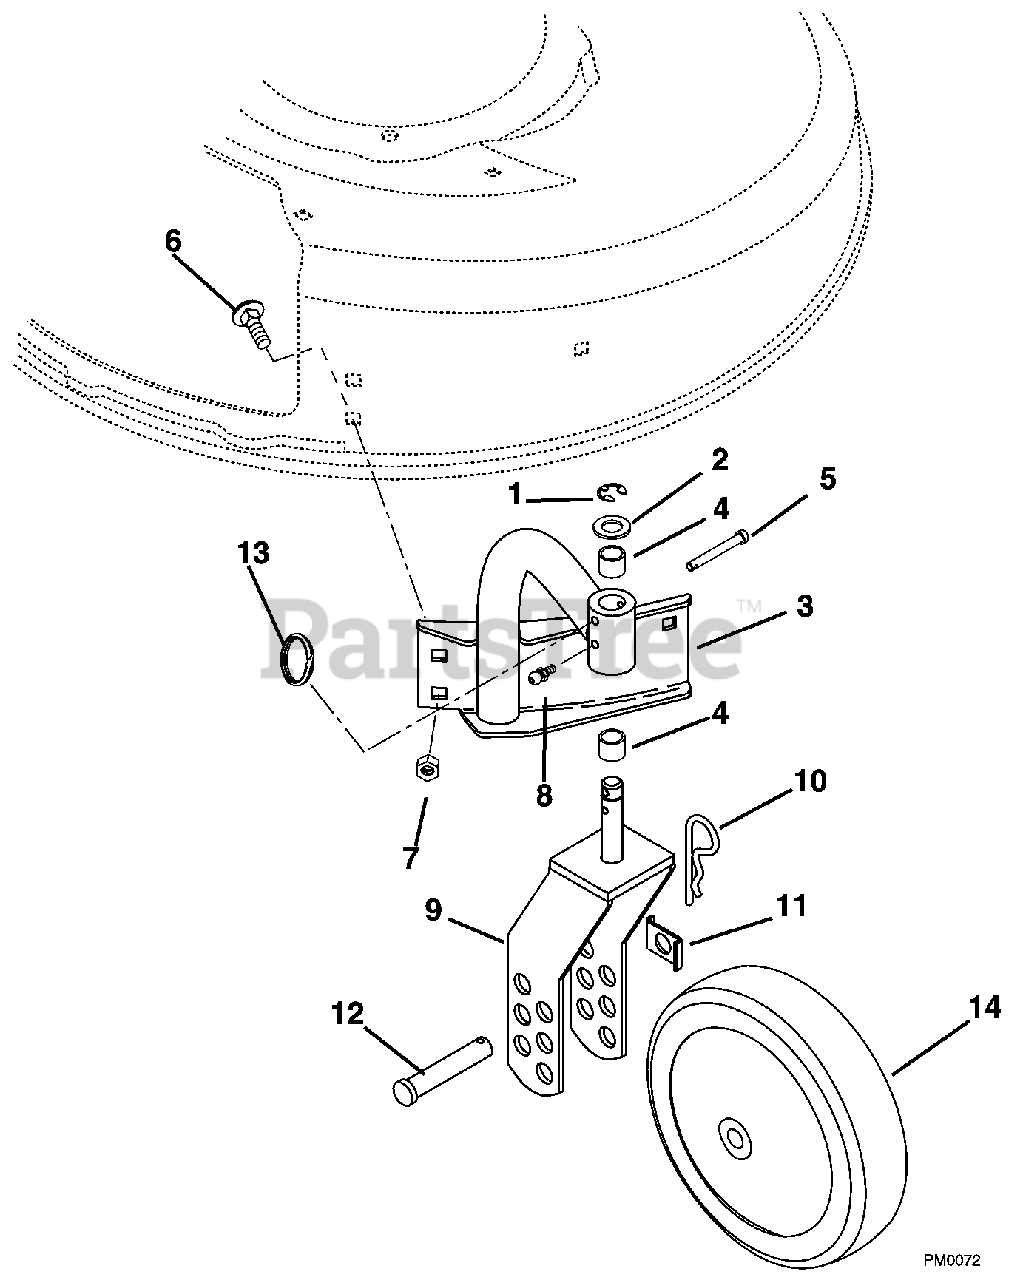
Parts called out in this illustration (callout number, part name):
1	Ring-Retaining-External .625 x .042
2	Washer-Flat-Steels .630 x 1.005 x .062
3	Right Mount Arm Weldment
4	Bushing-Sleeve .625 x .750 x .500
5	Pin-Clevis .25 x 1.75
6	Bolt-Round Head Square Neck .31-18 x .50 Grade 5
7	Nut-Hex .312-18
8	Fitting-Lube .25-28 x .256
9	Wheel Yoke Weldment
10	Pin-Hair External .12 x .31 x 2.37
12	Pin-Clevis .494 x 2.62
13	Ring-Kickout
14	Wheel-7.50 O.D. Steel Swivel
